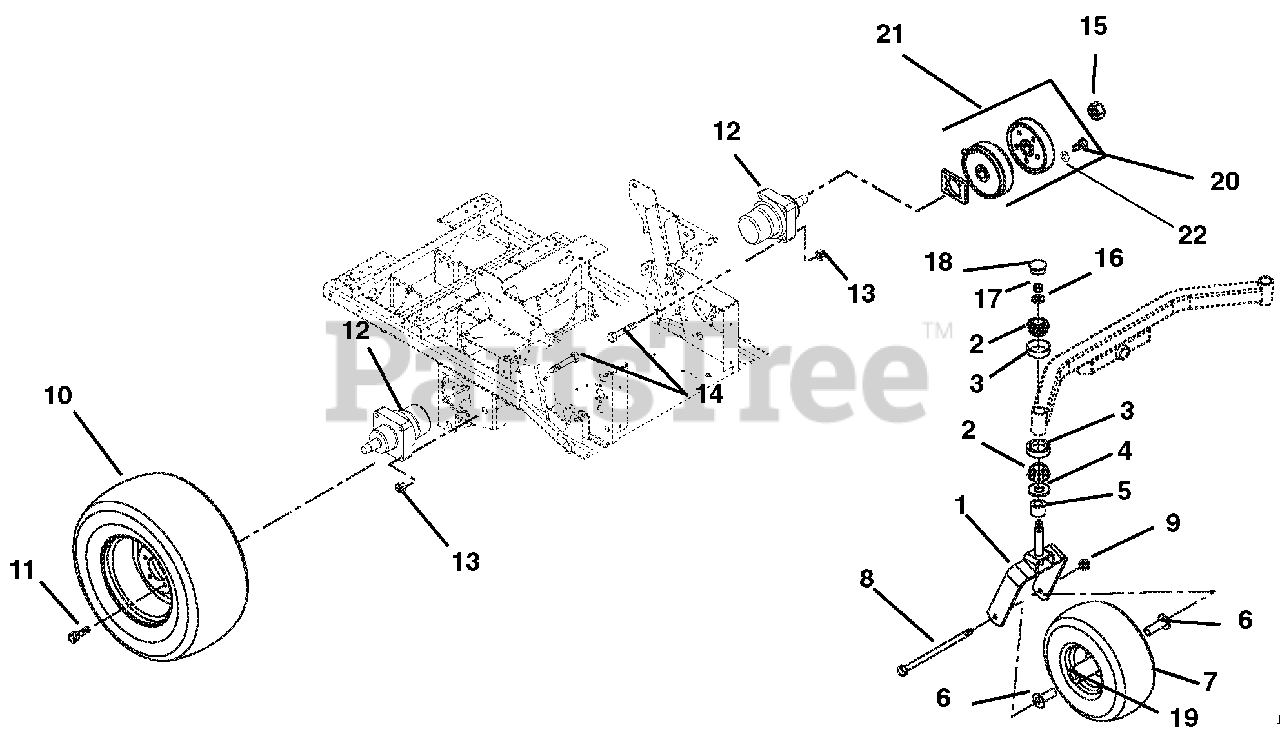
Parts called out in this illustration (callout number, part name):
1	Fork, Front
2	Bearing, Cone w/ Grease
3	Bearing, Cup 1.980 x .420
4	Bearing Seal 1.5 x 2 x .18
5	Spacer, PM, 1.03 I.D. x 1.5 O.D. x .375
6	Spacer, Wheel
7	Wheel/Tire Assembly 15 x 6-6
8	Bolt, Hex .50-13 x 9.00 Grade 5
9	Nut, Locking Center .50-13
10	Tire/Wheel Assembly 24 x 11.50-12
11	Bolt, Lug .50-20 x 1.38
12	Hydraulic Wheel Motor (Includes item 15)
13	Nut, Locking Top Flange .50-13
14	Bolt, Wheel Motor .50-13 x 2.75
15	Nut , Lock Jam Patch (Included with 12)
16	Washer, Flat Steel .812 x 1.50 x .135
17	Nut, Jam Center Lock .75-16
18	Cap, Dust
19	Bearing, 25mm I.D. x 52mm OD x 15mm
20	Bolt, Hex .31-18 x 1.5 Grade 8 EP30
21	Kit, Parking Brake Service
22	Washer, Lock .31 x .078 Reg.
